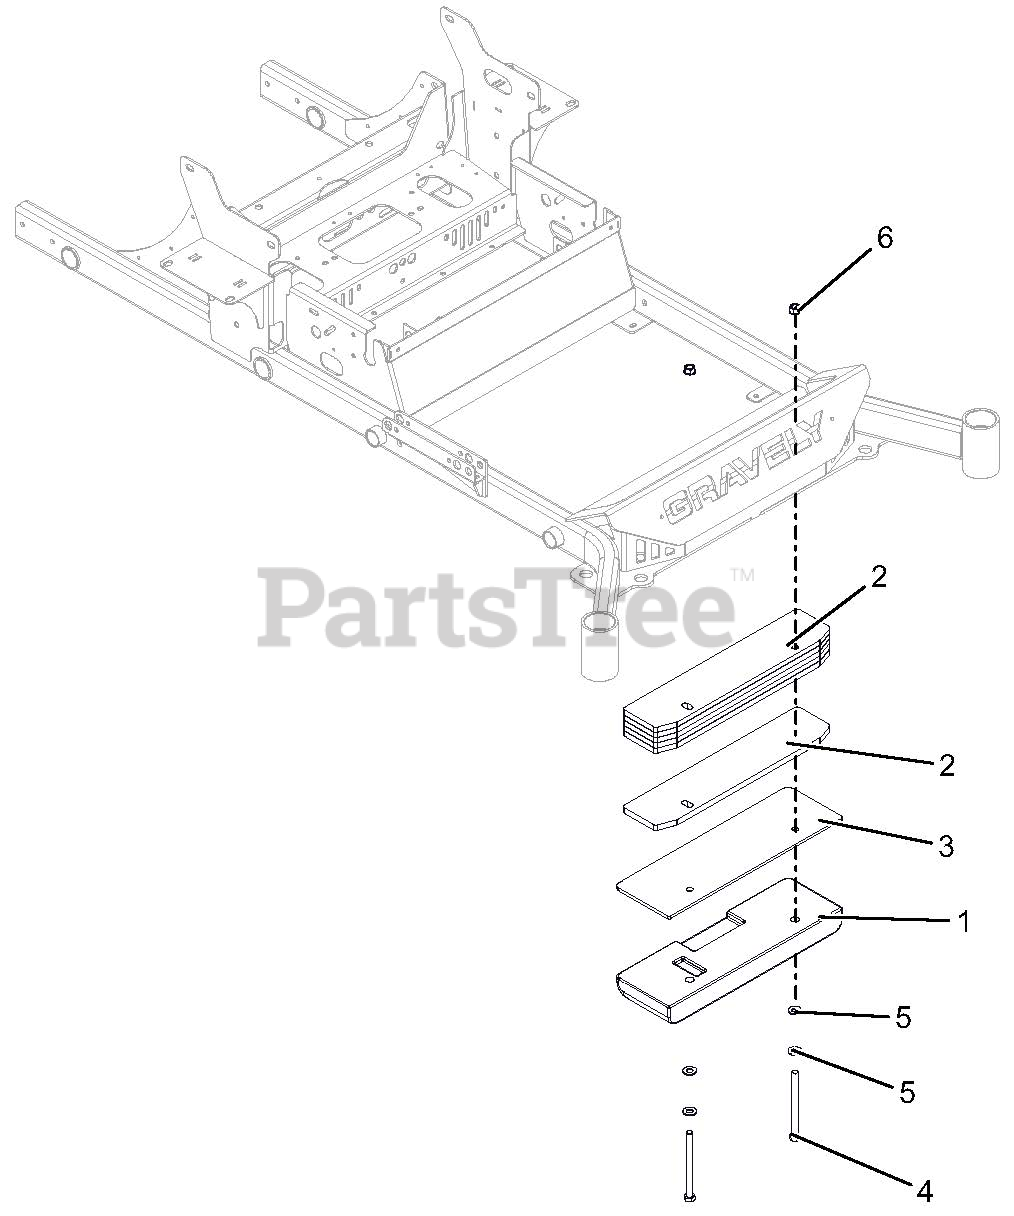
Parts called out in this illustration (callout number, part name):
1	WEIGHT, CAST IRON
2	WEIGHT, COUNTER
3	PLATE, COUNTERWEIGHT
4	BLT-HEX .50-13X6.00 GR5 YWZC
5	WSHR-FL-STL.531X1.06X.095YWZC
6	NUT, LK-TOP-FLG .50-13 YWZC
